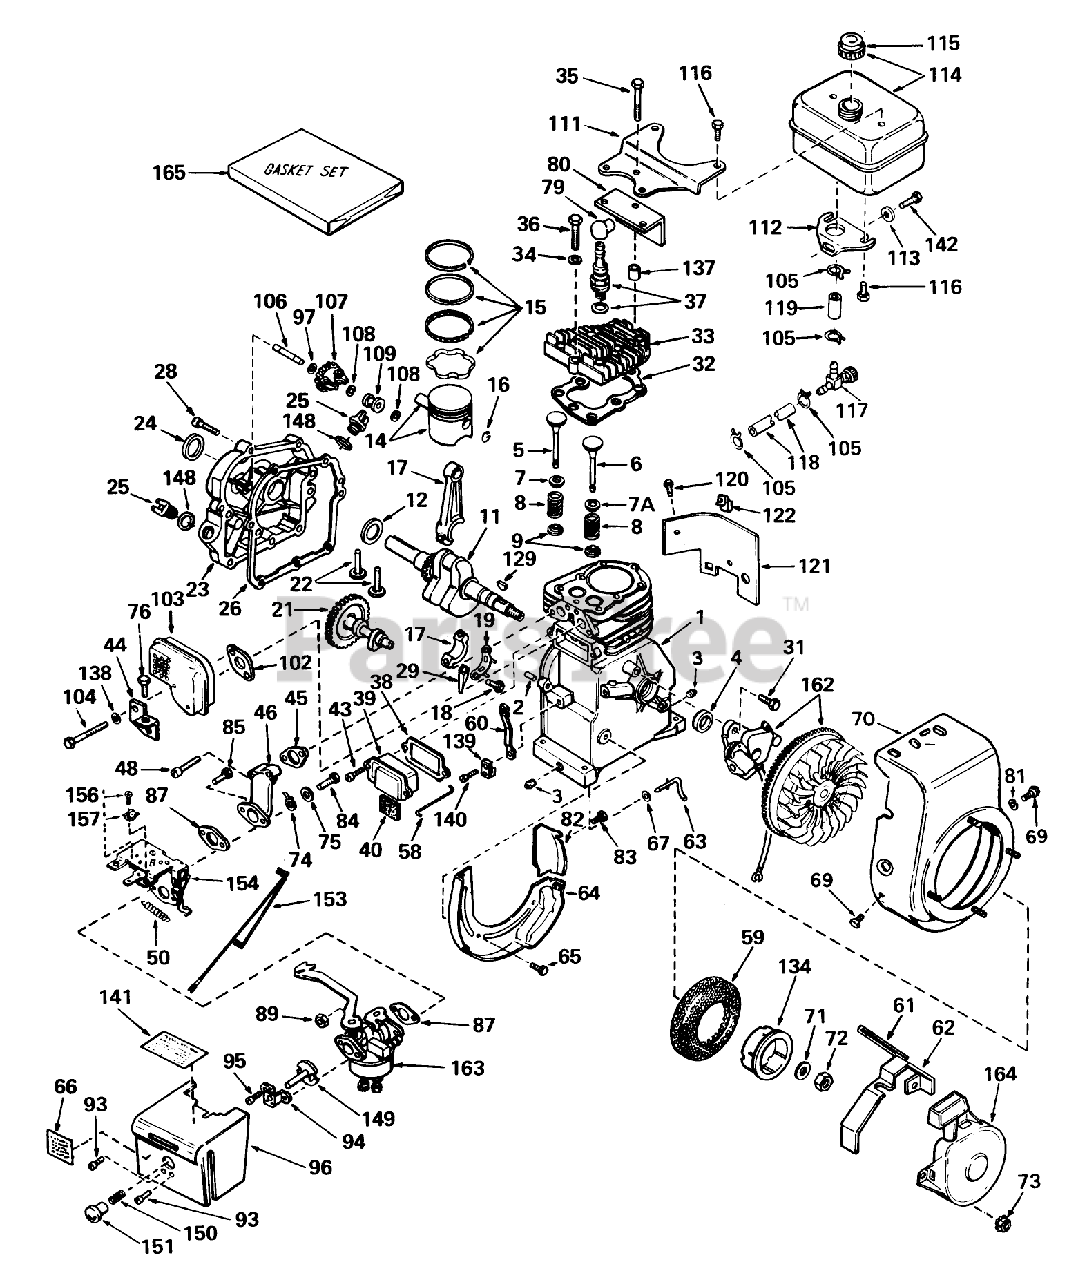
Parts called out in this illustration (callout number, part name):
1	Cylinder Assy. (Incl. Nos.2, 34)
2	Pin-Dowel
3	Plug-Drain, Oil (SQH 1/4-18)
4	Seal-Oil
5	Valve, Intake (Standard) (Incl. Nos. 7, 9 10)
5	Valve, Intake (1/32" Oversize) (Incl. Nos. 7, 9 10)
6	Valve, Exhaust (Standard) (Incl. Nos. 8, 9 10)
6	Valve, Exhaust (1/32" Oversize) (Incl. Nos. 8, 9 10)
7	Cap-Upper Valve Spring
7A	Cap, Upper Valve Spg (Exhaust)
8	Spring-Valve
9	Cap-Valve, Spring
11	Crankshaft Assy.
12	Washer-Thrust
14	Piston Pin Assembly (Incl. 2 of No. 14)(Std.)
14	Piston Pin Assembly (Incl. 2 of No. 14)(.010 Oversize)
14	Piston Pin Assembly (Incl. 2 of No. 14)(.020 Oversize)
15	Ring Set-Piston Std.
15	Ring Set-Piston .010 oversize
15	Ring Set-Piston .020 oversize
16	Ring-Retaining, Piston Pin
17	Rod Assy., Connecting (Incl. Nos. 18 19)
18	Connecting Rod Bolt
19	Plate Lock
21	Camshaft
22	Lifter-Valve
23	Cover, Cylinder (Incl. Nos. 24, 25, 106 148)
24	Seal-Oil
25	Plug-Fill, Oil
26	Gasket-Cylinder Cover
28	Screw
29	Dipper-Oil
31	Screw
32	Oil Fill Tube
33	Head Cylinder
34	Washer
35	Screw Hex Hd. Cap
36	Screw
37	Plug, Spark (J17LM or equiv.)
38	Gasket Breather
39	Breather Assembly (Incl. Nos. 52 84)
40	Element-Breather
43	Screw
44	Bracket-Cover, Carburetor
45	Gasket-Intake
46	Pipe-Intake
48	Screw (1/4-20 x 1-19/32)
50	Spring-Extension
58	Link, Governor to Throttle
59	Screen-Starter
60	Lever, Governor
61	Seal, Snowguard
62	Guard, Starter
63	Rod-Governor
64	Baffle-Blower Housing
65	Screw (1/4-20x19/32)
66	Decal, Instruction
67	Washer-Flat
69	Screw
70	Housing Blower
71	Washer-Spring
72	Hex Nut
73	Nut and Lock Washer (1/4-28)
74	Clip, Grounding
75	Washer
76	Screw (10-24 x 3/8)
79	Cover-Spark Plug
80	Baffle-Heat
81	Washer
82	Baffle-Extension
83	Screw-Hex Washer Hd.
85	Screw-Fil. Hd.
87	Gasket
89	Nut and Lock Washer (1/4-28)
93	Screw (8-32 X 5/16)
94	Bracket-Choke
95	Screw (10-32 x 1/2)
96	Cover, Carburetor
97	Washer-Flat
102	Gasket-Exhaust
103	Muffler
104	Screw-Fil. Hd.
105	Clamp-Line, Fuel
106	Shaft-Governor
107	Governor Gear ASM
108	Ring-Retaining
109	Spool-Governor
111	Bracket, Fuel tank
112	Bracket, Fuel Tank Lower
113	Washer
114	53023/VAR.10/16HP O
115	Cap, Fuel
116	Screw (1/4-15x7/8)
117	Valve-Shut Off
118	Line-Fuel
119	Line-Fuel (8.62)
120	Screw
121	Extension-Blower
122	51004 GIL ROTARY TI
129	Key Flywheel
134	Cup, Starter
137	pacer
138	Washer
139	Clamp-Lever, Governor
140	Screw
141	Decal, Operating
142	Screw (1/4-20 X 5/8)
148	Gasket
149	Plate, Choke
150	Spring, Compression
151	Knob, Choke
153	Wire, Ground
154	Bracket Assy., Speed Control (Remote)
156	Screw (10-32 x 3/8)
157	Conduit
162	Decal-Fuel Instructions
163	Carburetor (Incl. 1 of No. 87)
164	Starter Assy., Rewind
165	Gasket Set
